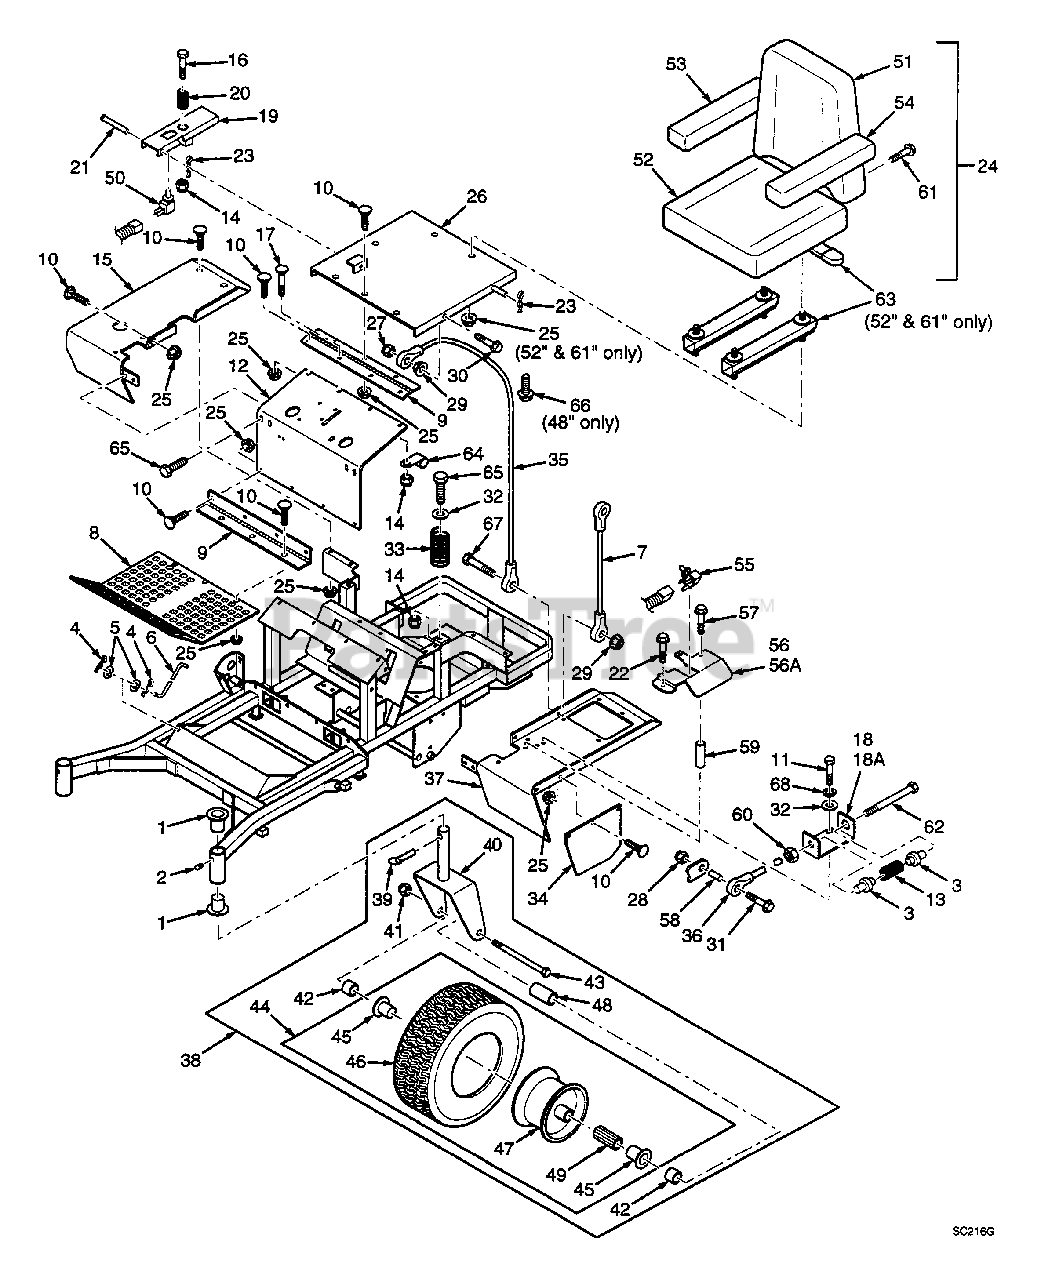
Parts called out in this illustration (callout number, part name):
1	Bushing
2	Grease Fitting
3	Bushing, Spring Keeper
4	Hair Pin, .08 Diameter x 1-3/16"
5	Flatwasher, 3/8" (.391 x .73S x .105)
6	Rod, Foot Plate Latch
7	Cable, Seat Stop
8	Foot Plate
9	Hinge
10	Bolt, Camage 5/16-18 x 3/4"
11	Bolt, Serrated Flange Hex Head 5/16-18 x 3/4"
12	Kick Plate
13	Neutral Return Spring
14	Nut, Elastic Stop 5/16-18
15	Fender Assembly, RH
16	Bolt, Hex Head 5/16-18 x 3-3/4"
17	Bolt, Carriage 5/16-18 x 1"
18	Retainer, Neutral Spring, LH
18A	Retainer, Neutral Spring, RH
19	Seat Switch Bracket
20	Spring
21	Clevis Pin
22	Bolt, Serrated Flange Hex Head 5/16-18 x 1/2"
23	Hair Pin, Cotter
24	Seat Assembly w/Adjuster Rails
25	Nut, Serrated Flange Hex 5/16-18
26	Seat Base
27	Nut, Elastic Stop 1/4-20
28	Nut, Elastic Stop 3/8-16
29	Nut, Serrated Flange Hex 1/4-20
30	Bolt, Serrated Range Hex Head 1/4-20 x 1"
31	Bolt, Hex Head 3/8-16 x 2-1/2"
32	Flatwasher, 5/16" (.313 x.875 x .083)
33	Seat Spring
34	Fender Panel, LH
35	Cable, Seat Stop
36	Ball Joint, Neutral
37	Fender, LH
38	Caster Wheel Yoke Assembly
39	Quick Pin
40	Caster Wheel Yoke
41	Nut, Elastic Stop 1/2-13
42	Spacer
43	Bolt, Hex Head 1/2-13 x 6-1/2"
44	Wheel Aesembly, Complete
45	Retainer
46	Tire Only
47	Rim Only
48	Sleeve
49	Roller Bearing
50	Seat Switch
51	Seat, Back Cushion
52	Seat, Bottom Cushion
53	Arm Pad, RH
54	Arm Pad, LH
55	Neutral Interlock Switch
56	Neutral Lock Bracket, RH
56A	Neutral Lock Bracket, LH
57	Bolt, Serrated Range Hex Head 5/16-18 x 2-3/4"
58	Spacer, Neutral Spring
59	Spacer, Neutral Lock Bracket
60	Nut, Hex 3/8-24 UNF
61	Bolt, Hex Head w/Washer, 1/4-20 x 3/4"
62	Bolt, Hex Head 3/8-24 x 6-1/2", UNF
63	Seat Adjustment, Track Set
64	Cable Clamp, .50 ID
65	Bolt, Hex Head 5/16-18 x 1"
66	Bolt, Serrated Range Hex Head 5/1 6-18 x 1"
